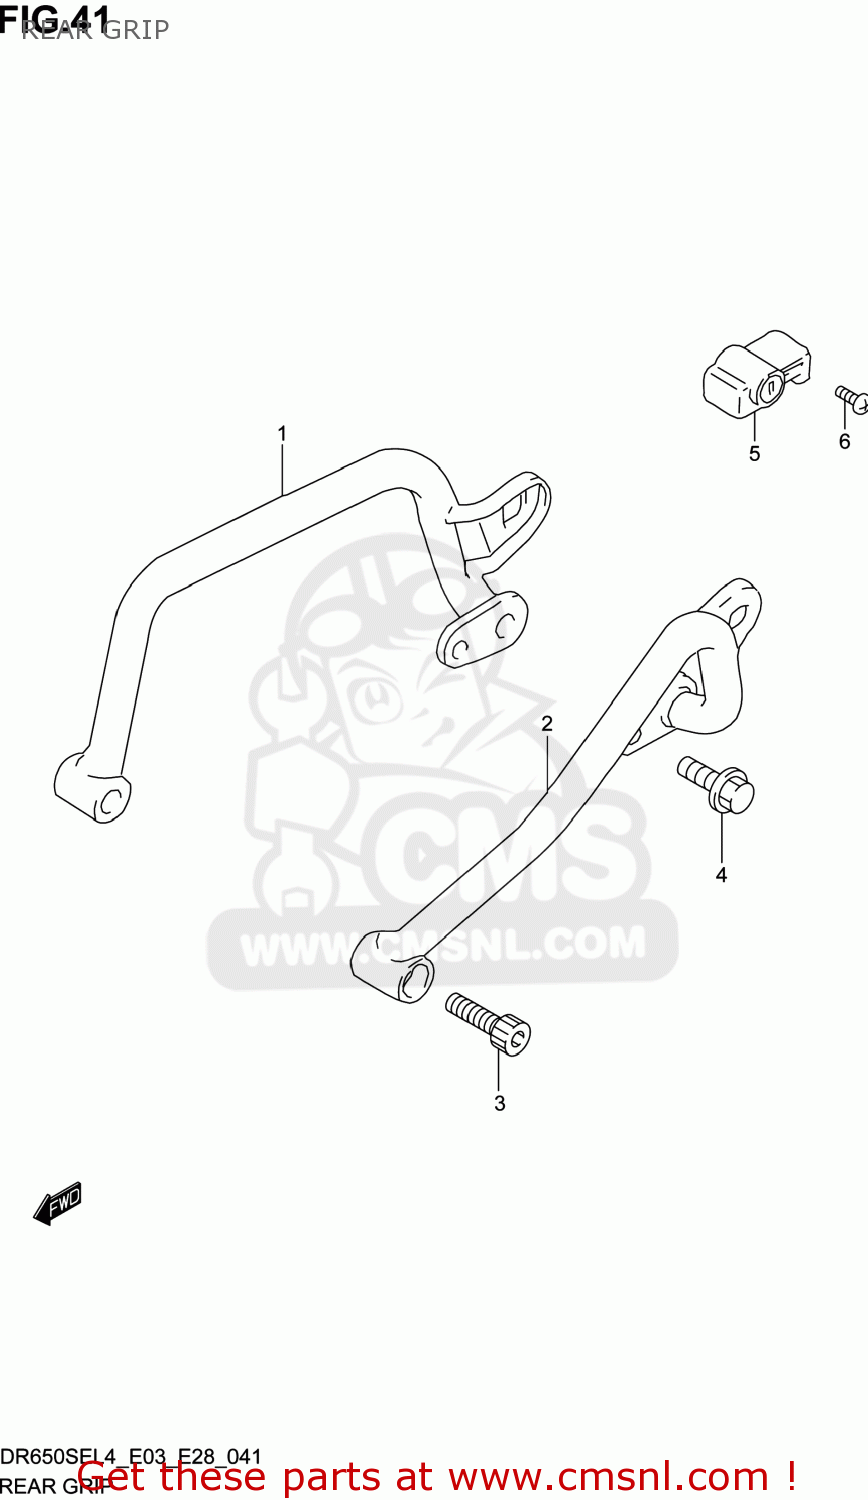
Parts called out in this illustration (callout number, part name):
1	GRIP,RR,R
2	GRIP,RR,L
3	BOLT
4	BOLT
5	LOCK SET,HELMET
6	SCREW(6X14)
